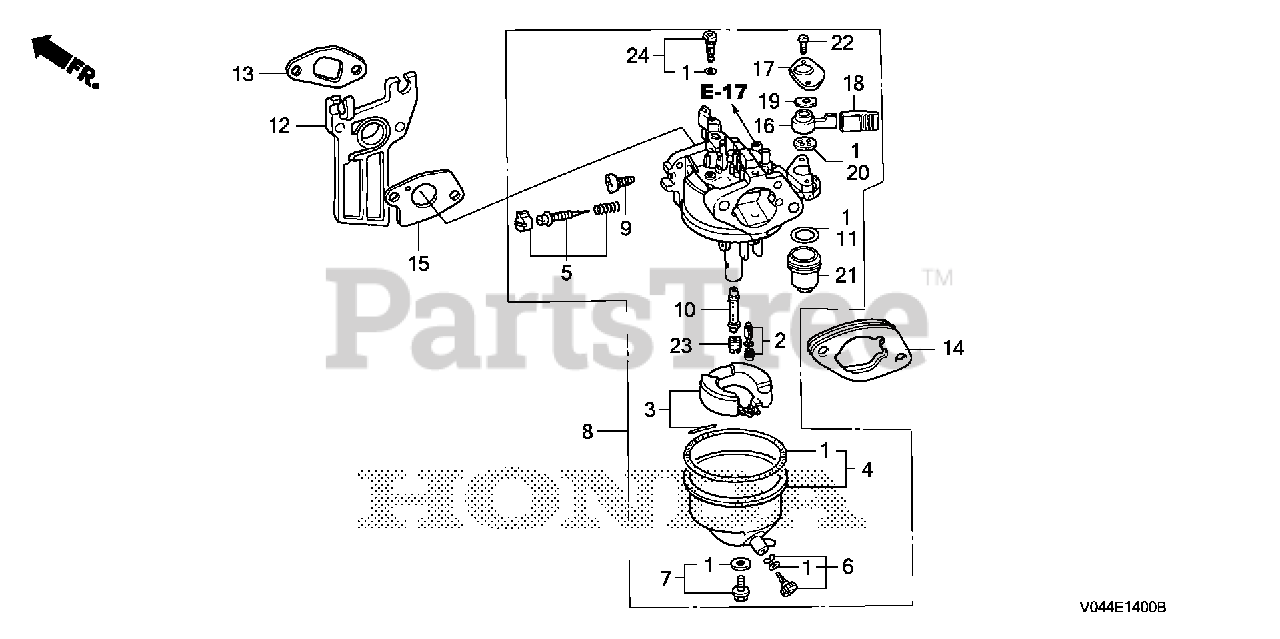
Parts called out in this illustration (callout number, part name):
1	GASKET SET (CARBURETOR NO.)
2	VALVE SET, FLOAT (CARBURETOR NO.) (SEAT NOT INCLUDED)
3	FLOAT SET
4	CHAMBER SET, FLOAT
5	SCREW SET (Honda Code 4219879). (CARBURETOR NO.)
6	SCREW SET, DRAIN (CARBURETOR NO.)
7	SCREW SET B
7	SCREW SET
8	CARBURETOR ASSY. (BE64Q A)
9	SCREW, THROTTLE STOP
10	NOZZLE, MAIN
11	GASKET, FUEL STRAINER CUP
12	INSULATOR, CARBURETOR
13	GASKET, INSULATOR
14	SPACER, CARBURETOR
15	GASKET, CARBURETOR
16	LEVER, VALVE
17	PLATE, LEVER SETTING (CARBURETOR NO.)
18	CAP, LEVER
19	SPRING, PETCOCK LEVER (CARBURETOR NO.)
20	GASKET, VALVE
21	CUP, FUEL STRAINER
22	SCREW, PAN (3X6)
23	JET, MAIN (#72) (CARBURETOR NO.)
23	JET, MAIN (#75) (CARBURETOR NO.)
23	JET, MAIN (#70)
24	JET SET, PILOT (#45)
